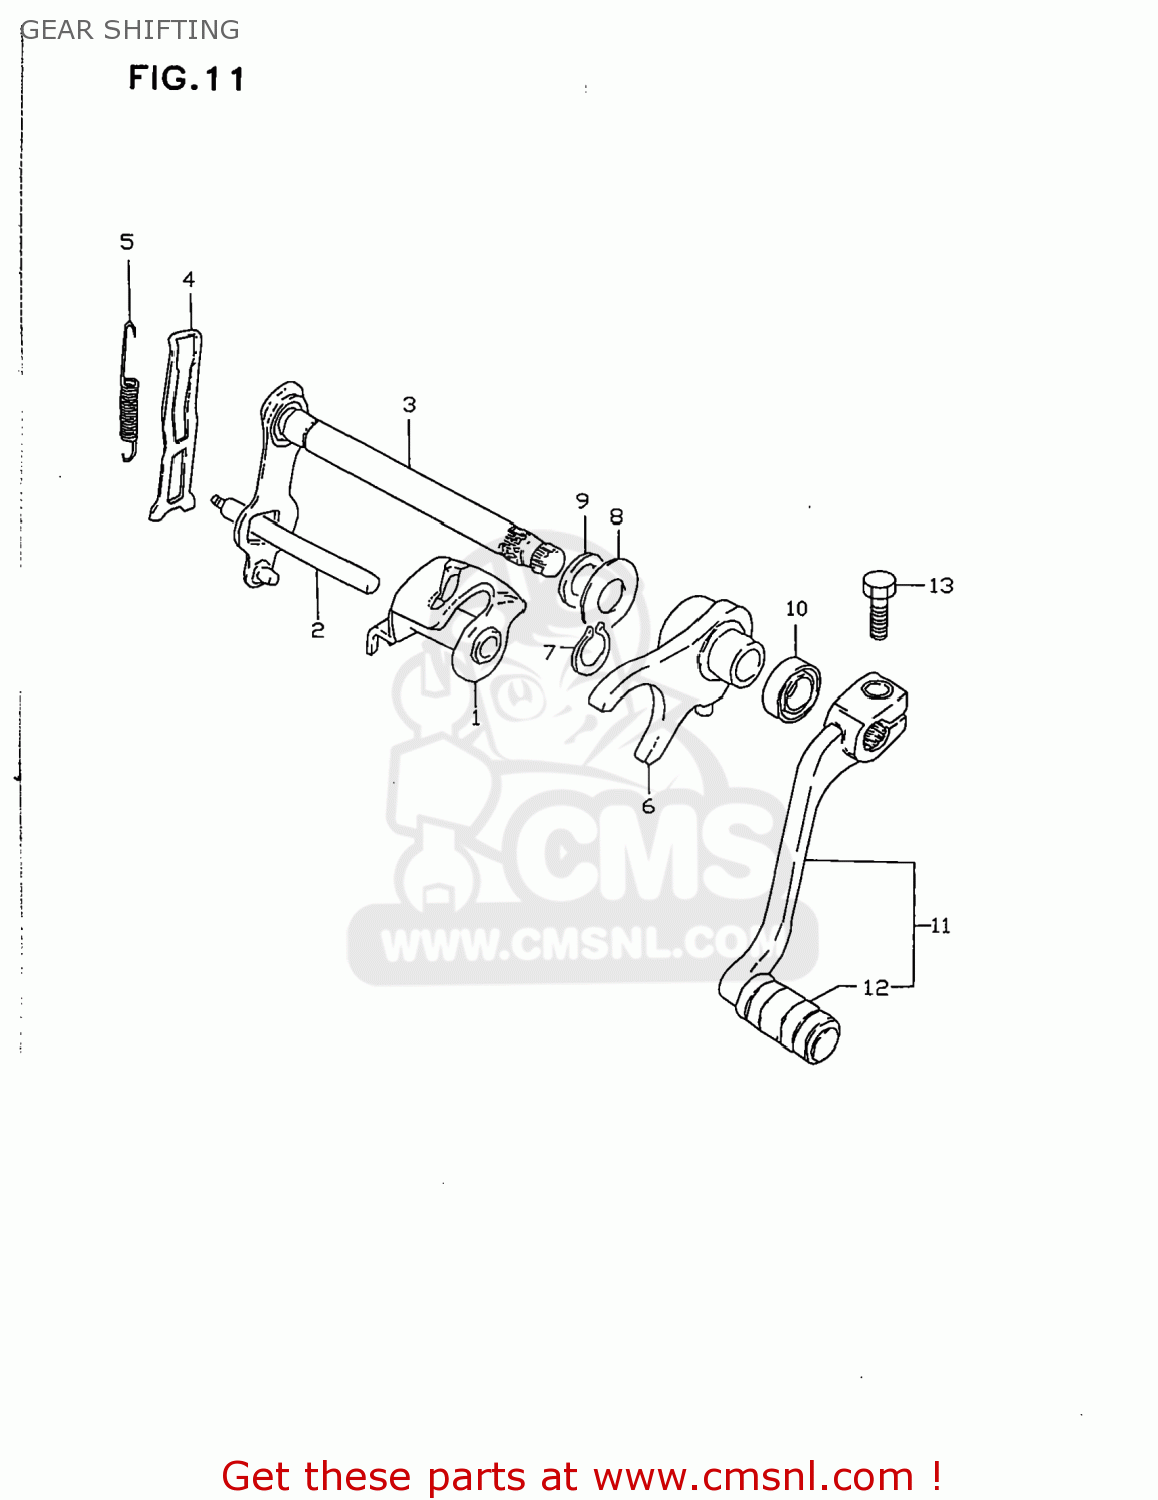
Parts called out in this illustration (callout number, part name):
1	CAM,GEAR SHIFT
2	SHAFT,GEAR SHIFT CAM
3	SHAFT,GEAR SHIFT
4	ARM,GEAR SHIFT CAM STOPPER
5	SPRING
6	FORK,GEAR SHIFT NO.1
7	CIRCLIP,12 MM
8	WASHER
9	WASHER
10	OIL SEAL
11	LEVER ASSY,GEAR SHIFT
12	RUBBER,GEAR SHIFT PEDAL
13	BOLT
